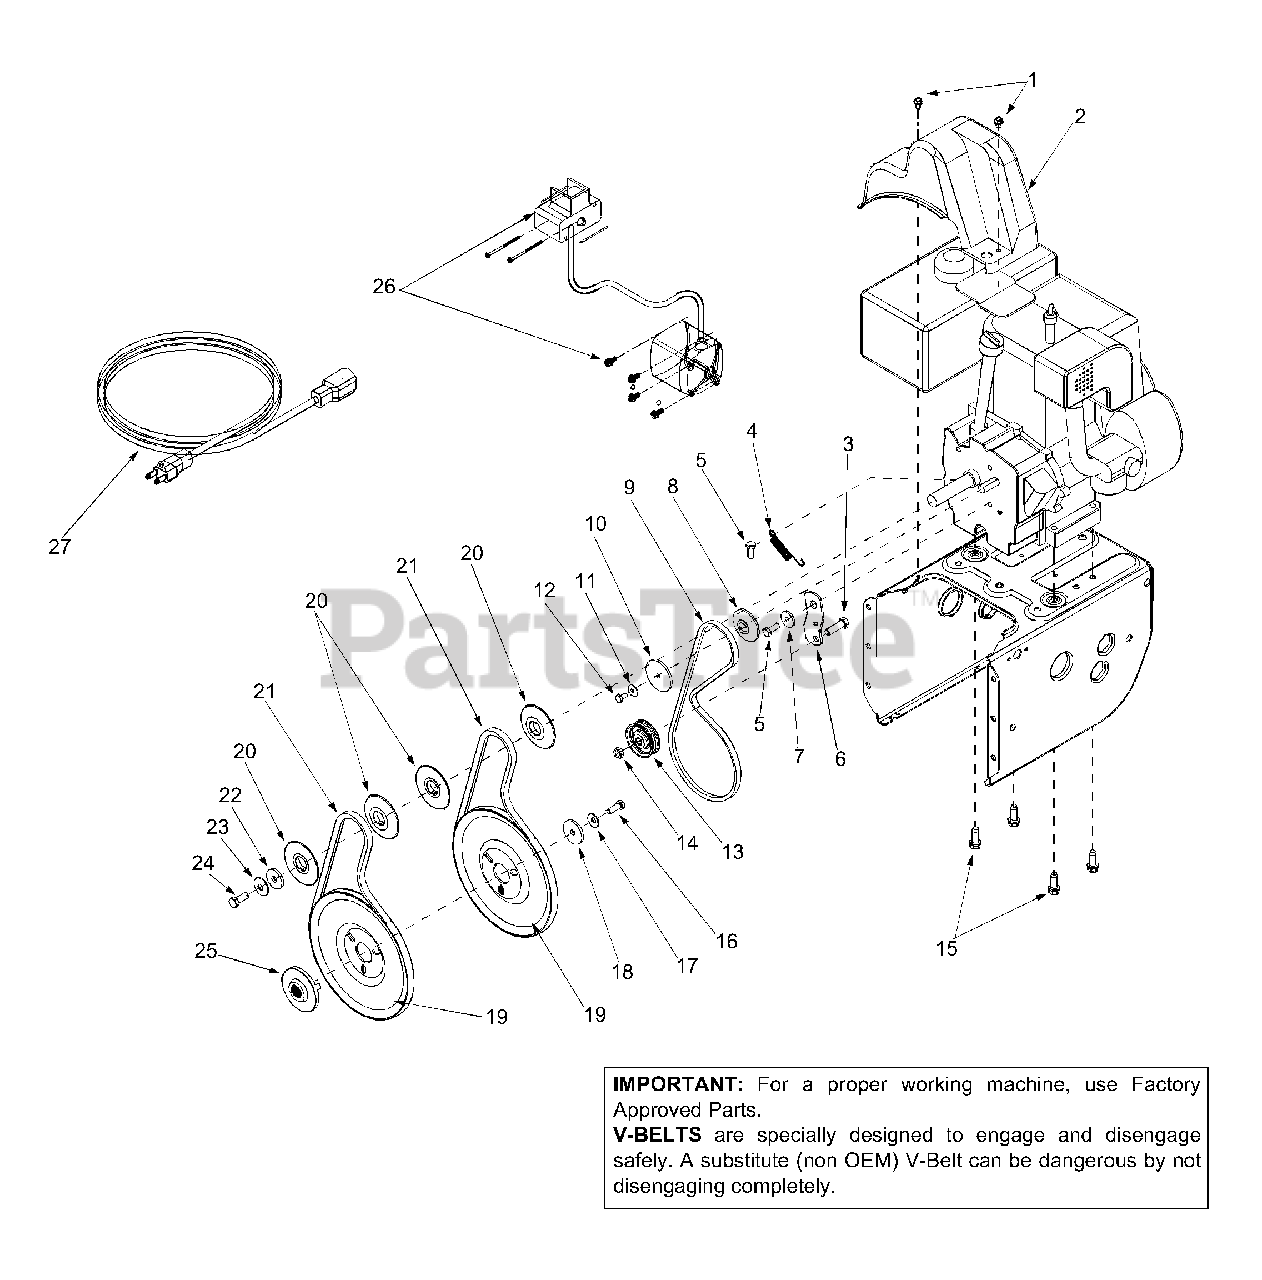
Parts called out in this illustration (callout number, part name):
1	Hex Washer Screw 1/4-20 x.50
2	Belt Cover
3	Hex Cap Screw 3/8-16 x 1.25
4	Extension Spring
5	Hex Screw 5/16-24 x.75
8	Pulley Half
9	Belt
10	Pulley Half
11	Bell Washer
12	Hex Cap Screw
13	Flat Idler
14	Lock Jam Nut 3/8-16
15	Hex Washer Screw 3/8-16 x 1.0
16	Hex Lock Screw 5/16-24 x.875
17	Bell Washer.340 ID x.872 OD
18	Flat Washer.341 ID x.50 OD
19	Auger Pulley
20	Pulley Half
21	V-Belt
22	Flat Washer
23	Bell Washer.39 ID x 1.13 OD
24	Hex Cap Screw 3/8-24 x.875
25	Pulley Adapter
26	Electric Start
27	Extension Cord, Three-Prong
